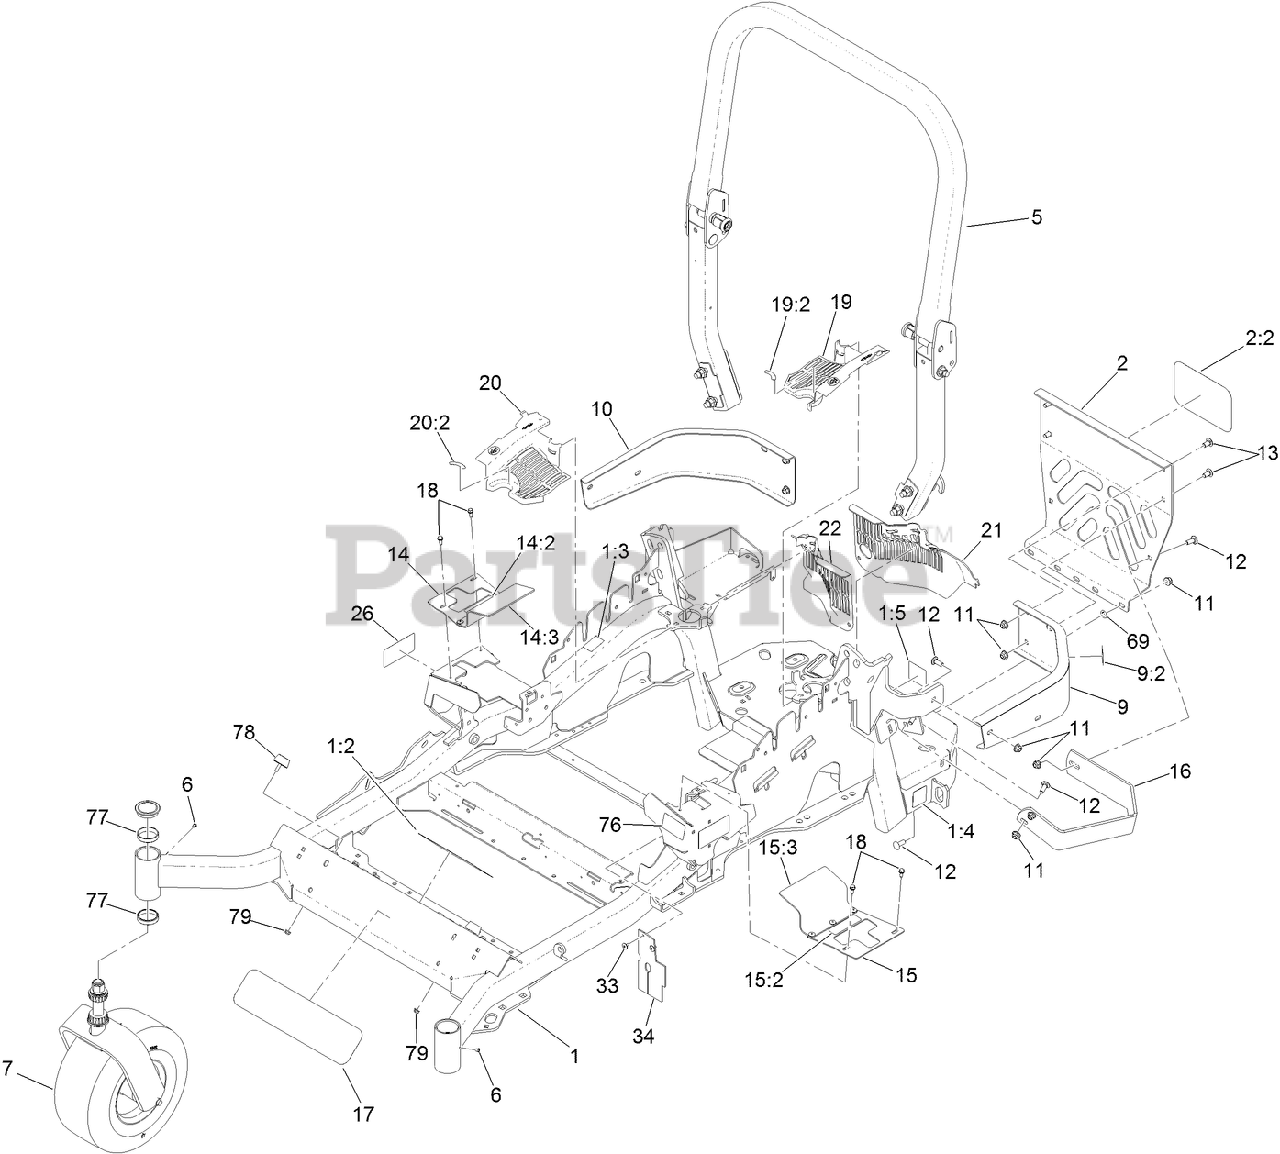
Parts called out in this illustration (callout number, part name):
1	MAINFRAME ASM
1:2	DECAL-DANGER
1:3	DECAL-WARNING
1:4	DECAL-HAZARD, PINCHED FINGER
1:5	DECAL-SPARK ARRESTER
2	REAR GUARD ASM
2:2	DECAL
5	ROPS ASM
7	Deck ASM
9	LH BUMPER ASM
9:2	DECAL-WARNING
10	BUMPER-RH
11	NUT-HF, NI
12	SCREW-CARR
13	SCREW-CARR
14	RH MOTION CONTROL COVER ASM
14:2	DECAL-CONTROL, MOTION
14:3	FLAP-RUBBER
15	LH MOTION CONTROL COVER ASM
15:2	DECAL-CONTROL, MOTION
15:3	FLAP-RUBBER
16	GUARD-MUFFLER
18	SCREW-HWH
19	LH HYDRO GUARD ASM
19:2	DECAL-OIL, HYDRO
20	RH HYDRO GUARD ASM
20:2	DECAL-OIL, HYDRO
21	GUARD-HYDRO REAR, LH TRIM
22	GUARD-HYDRO, REAR (RH)
33	RIVET-POP
34	DEFLECTOR-AIR FLOW
69	NUT-PUSH
76	DECAL-FUEL FILL, CE
77	CUP-BEARING
78	BUMPER
79	NUT-HF
